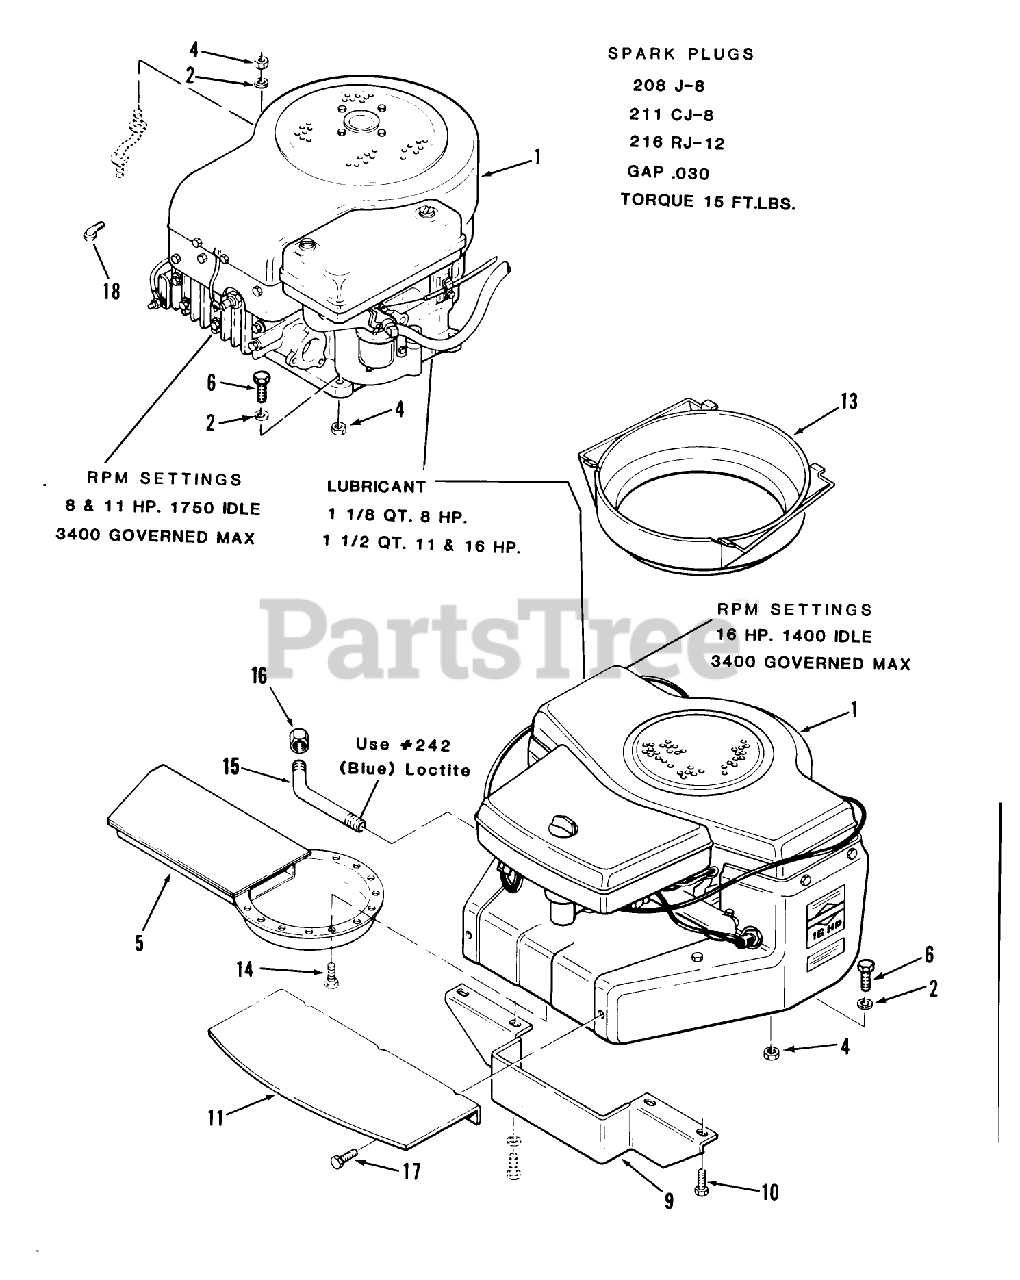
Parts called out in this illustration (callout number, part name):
1	Engine-08HP-BS Model 191707, Type 2153-01 208-3 Only
2	WASHER 5/16 SAE
13	DUCT-AIR INTAKE
18	STREET ELBOW 45DEGRE
